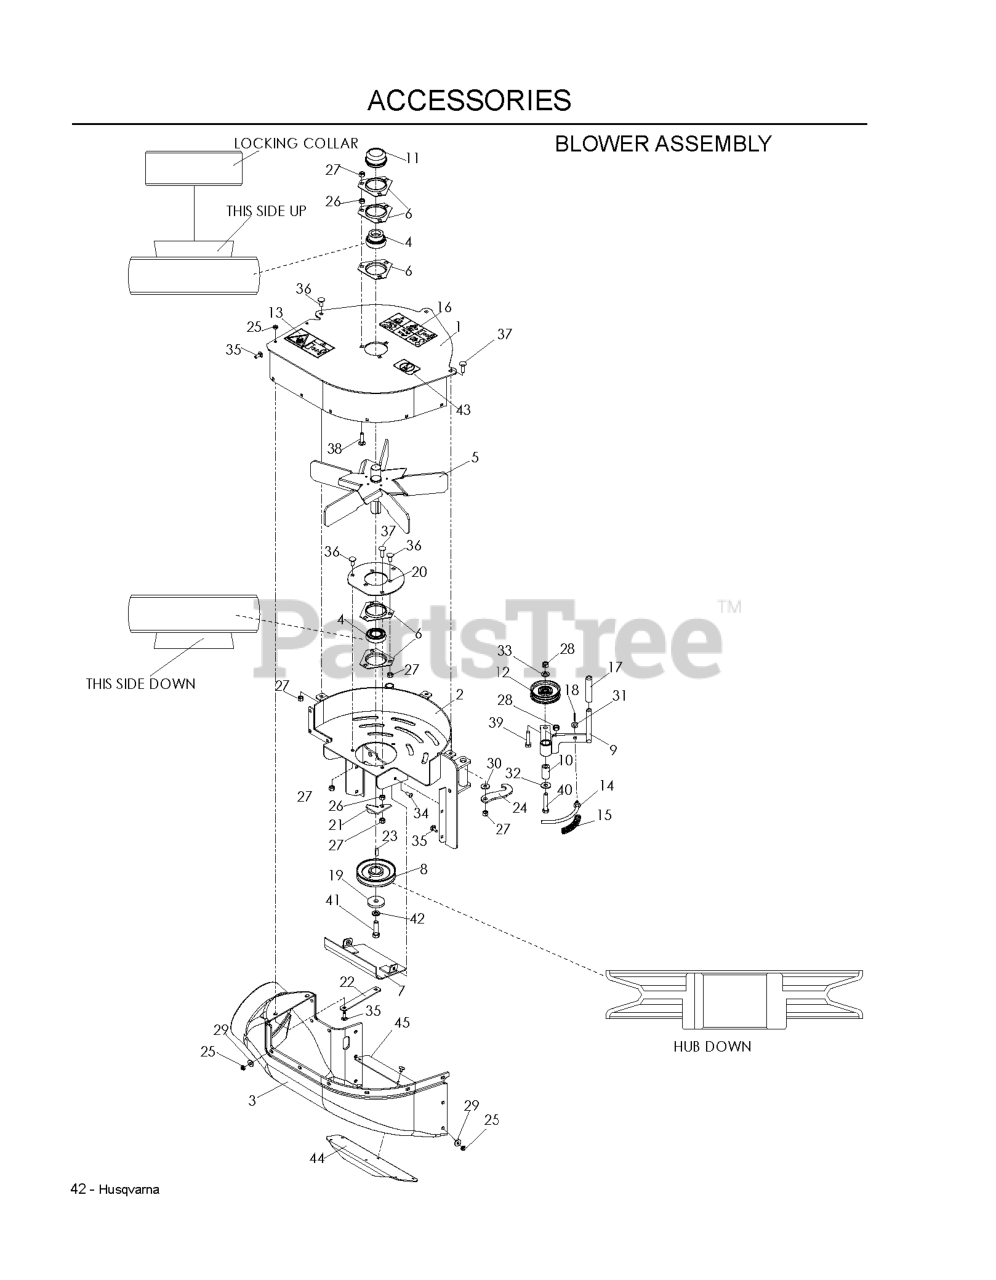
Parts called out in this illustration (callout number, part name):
1	FAN COVER W/DECALS
2	BLOWER HOUSING WELDMENT
3	LOWER HOUSING
4	BEARING KIT-2 PCS
5	FAN WELDMENT
6	BRG FLANGE
7	COVER PLATE WELDMENT
10	BUSHING, SLEEVE
11	GREASE CAP
13	EURO DECAL, IMPELLER
14	SPRING ROD WLDMNT
16	DECAL, EURO WARNING
18	COTTER PIN 3/32 X 3/4
19	SPINDLE WASHER
20	BEARING PLATE - BLACK
21	BELT GUIDE
22	BACKING (BLACK)
23	KEY 1/4 SQ X 3/4
24	IDLER ARM KEEPER
25	JAM NUT 1/4C (2 2 PW01)
26	NUT 5/16C HEX
27	NUT 5/16 NYLOC
28	NUT 3/8C CENTERBLOCK
29	WASHER 1/4 FLAT
30	WASHER 5/16 FLAT
31	FLAT WASHER 5/16 SAE
32	WASHER 3/8 FLAT
33	WASHER 3/8 SAE FLAT
34	SCR 1/4-20 X 5/8 BTN SKT HD ZD
35	RHSNB 1/4C X 3/4
36	BOLT 5/16C X 3/4" CARRIAGE
37	RHSNB 5/16C X 1
38	BOLT, CARRIAGE 5/16X1-1/4
39	HCS 3/8C X 1 1/2
40	HCS 3/8C X 2
41	HCS 7/16F X 1 1/2
42	WASHER 7/16 LOCK
43	DECAL, NO STEP
44	BLOWER SUPPORT
45	PLATE, BLOWOUT
